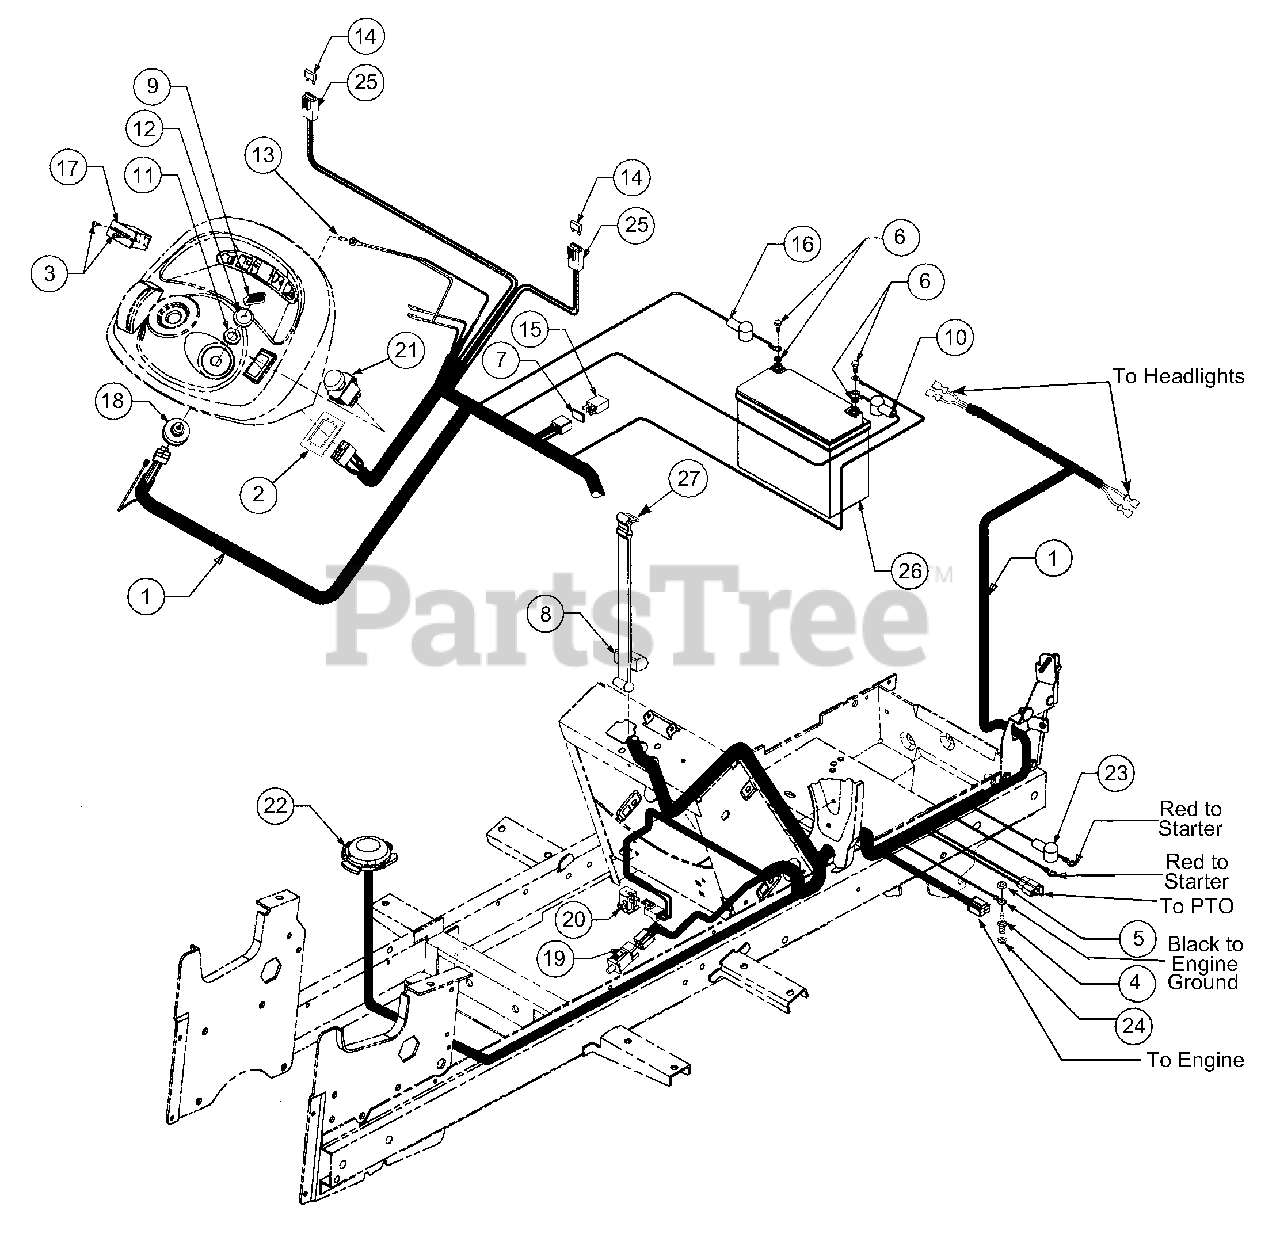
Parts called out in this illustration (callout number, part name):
1	Wire Harness, Main
2	Bracket, PTO Switch Retainer
3	Screw, Truss Hd Tapp, #6 x .62
4	Stud, Ground
5	Nut, Hex, 5/16-18 GR5
6	Battery Cable Hardware Screw
7	Gasket, Silicone
8	Strap, Battery Retainer
9	Key, Ignition (Set of 2)
10	Cover, Terminal Black
11	Nut, Ignition Switch
12	Cap, Ignition Switch
13	Bulb, Indicator
14	Fuse, 25 Amp
15	Relay
16	Cover, Terminal Red
17	Hour Meter
18	Switch, Ignition
19	Switch, Interlock (Brake)
20	Switch, Snap Mount - Normally Closed
21	Switch, PTO
22	Switch, Seat
23	Cover, Terminal Red
24	Washer, External Lock, 5/16
25	Holder, Fuse w/Mounting Clip
26	Battery
27	Hook, Wire Rectangular
